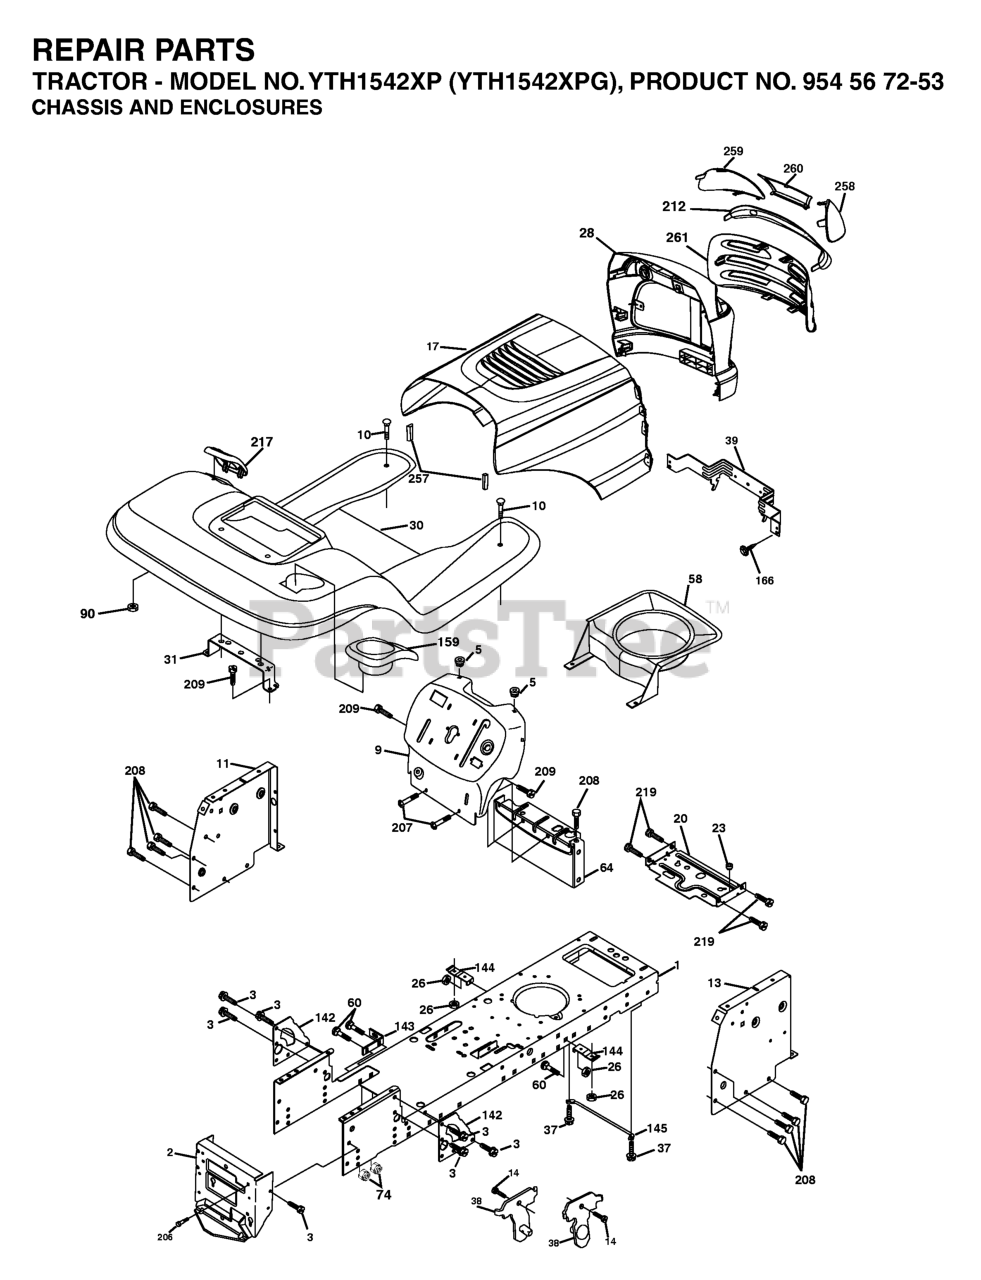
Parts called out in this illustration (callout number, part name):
1	CHASSIS STAMPING
2	DRAWBAR, 12GA
3	SCREW 3/8-16X3/4
5	BUMPER.RUBBER.HOOD
9	DASH SLKSCR
10	BOLT D
11	PANEL.DASH.LH.LTX
13	PANEL ASM, DASH RH
17	HOOD
20	PLATE MTG.BATTERY/FUEL TANK
23	BUSHING.SNAP.NYL.BLK.
26	NUT
28	GRILL/LEN.ASM.DL.HUSQ
30	FENDER
31	BRACKET.SUPPORT.FENDER
37	Screw 5/16-18 x 1/2 Hex, Self Tapping 5/16-18 x 1/2
38	BRACKET.ASM.PIVOT.MOWER.REAR
39	BRACKET PIVOT LASER
60	Bolt - Rd. Hd. Sq. Neckiage 3/8 16 x 3/4
64	DASH LOWER
90	NUT.PUSH.3/16
142	PLATE REINFORCEMENT
143	BRACKET, SWAY BAR
144	BRKT, FOOT REST
145	ROD PIVOT CHASSIS/HOOD
159	GREY CUP HOLDER
166	SCREW
206	SHOULDER BOLT 5/16-18TT
207	SCREW, 5/16-18 X 1/2
208	SCREW 3/8-16X1/2
209	SCREW, 3/8-16X3/4
212	INSERT.LENS.REFLECTIVE
217	CONSOLE FUEL WINDOW
219	SCREW
257	BUMPER.HOOD.LARGE.1.75"
258	LENS LH
259	LENS LH
260	COVER.LENS.HUSQ.( HAVE GRAY)
261	INSERT GRILLE
